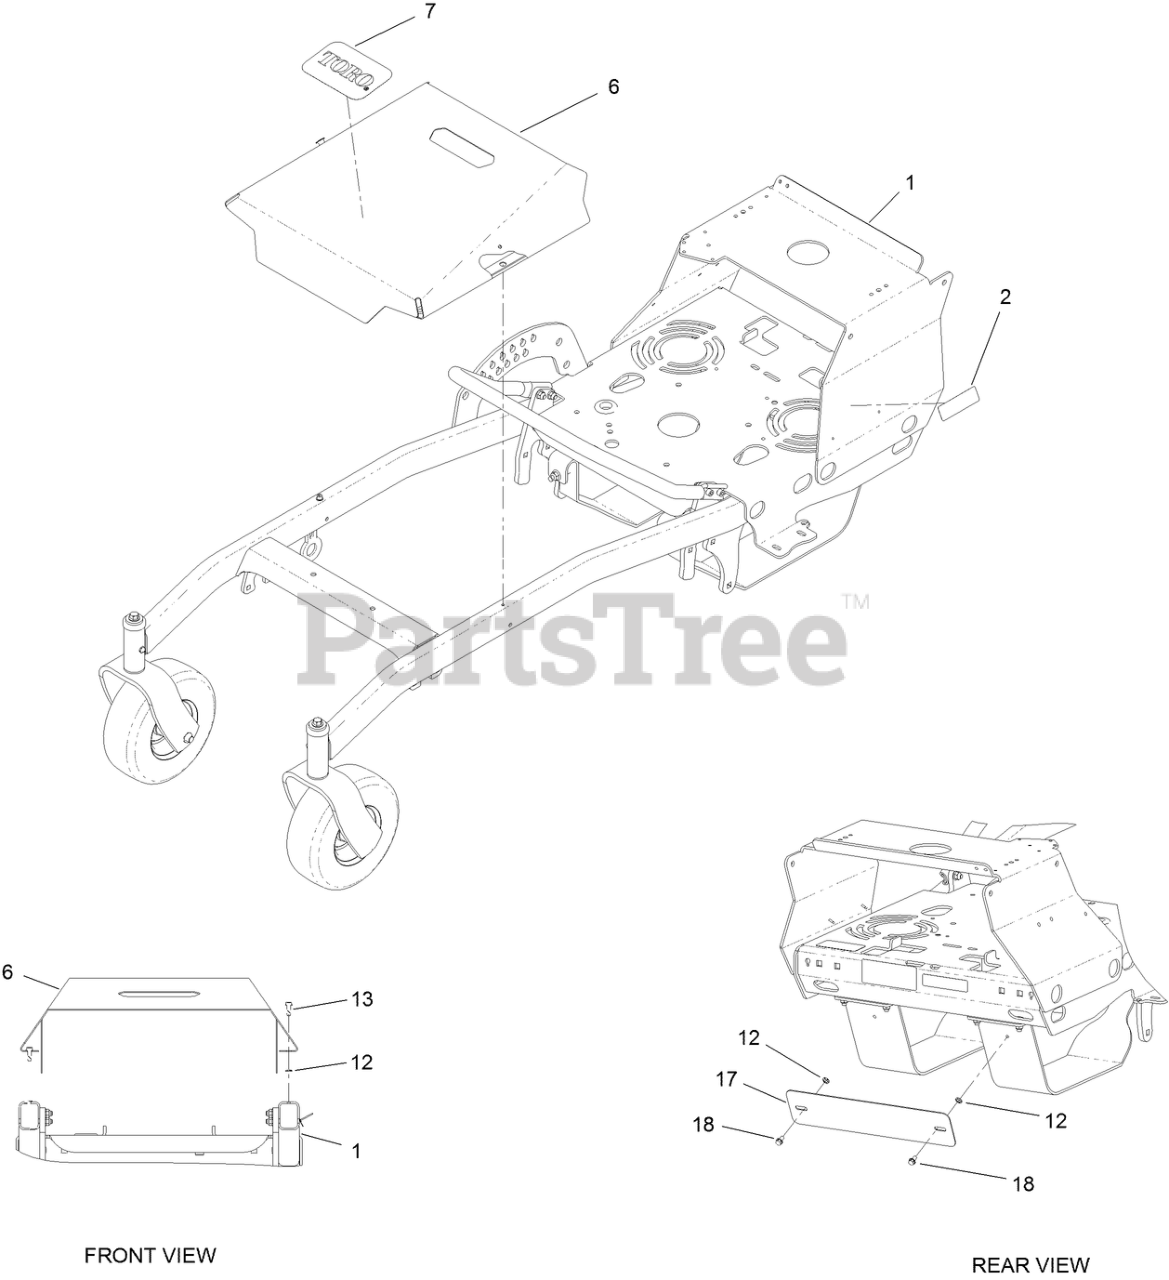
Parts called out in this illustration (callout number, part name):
1	FRAME ASSEMBLY
2	DECAL-EMISSIONS, EXPORT
6	COVER-DECK
7	DECAL
12	NUT-RETAINING
13	SCREW-HWHTF
17	PLATE-GUARD, INTL [BLACK]
18	SCREW-HWH
